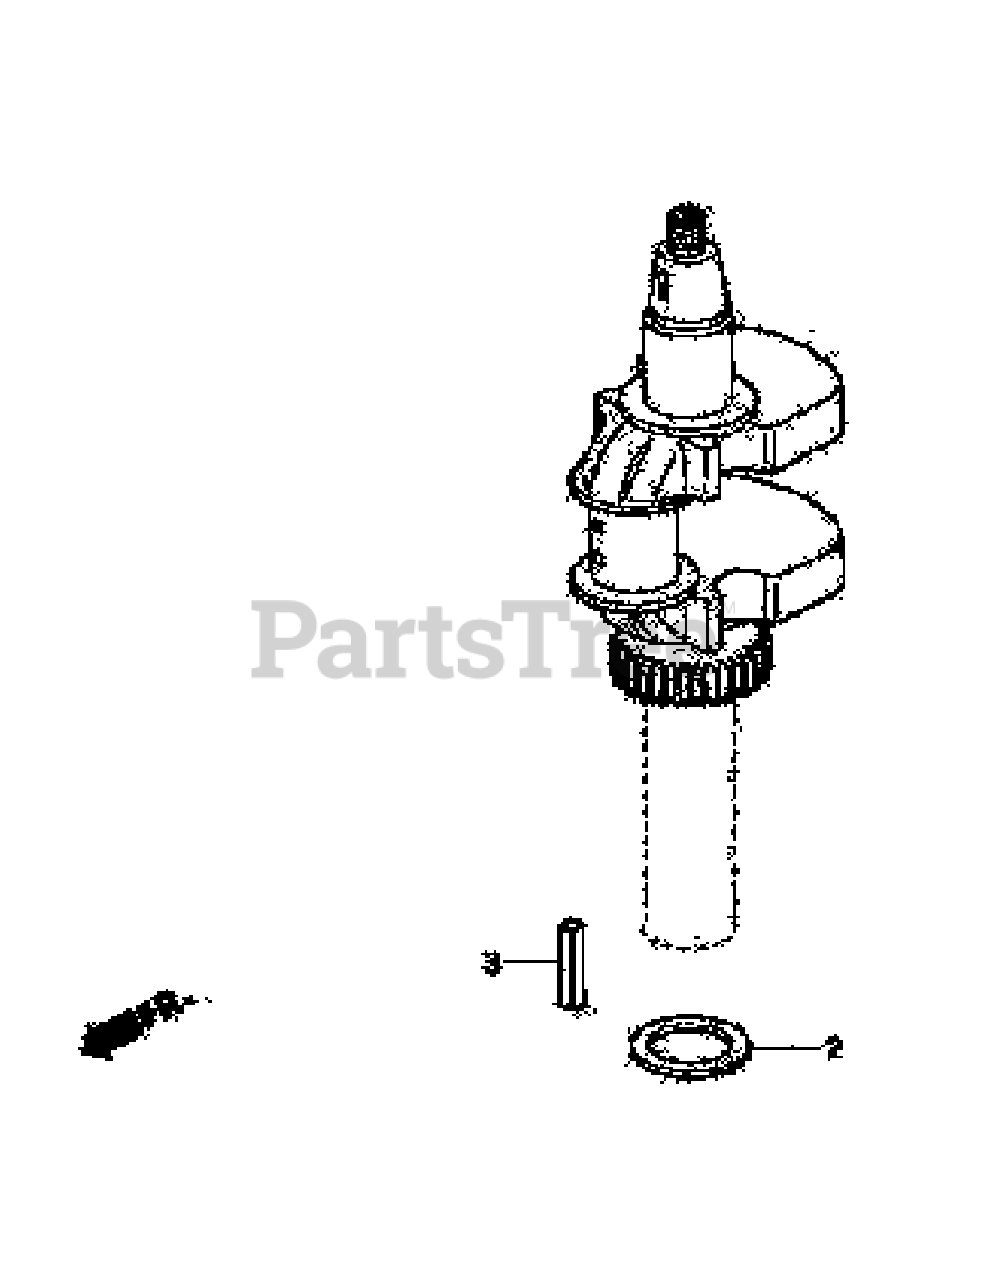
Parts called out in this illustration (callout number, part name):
1	Crankshaft
2	Crankshaft Thrust Washer
3	Key (1/4x1/4x2.75)
